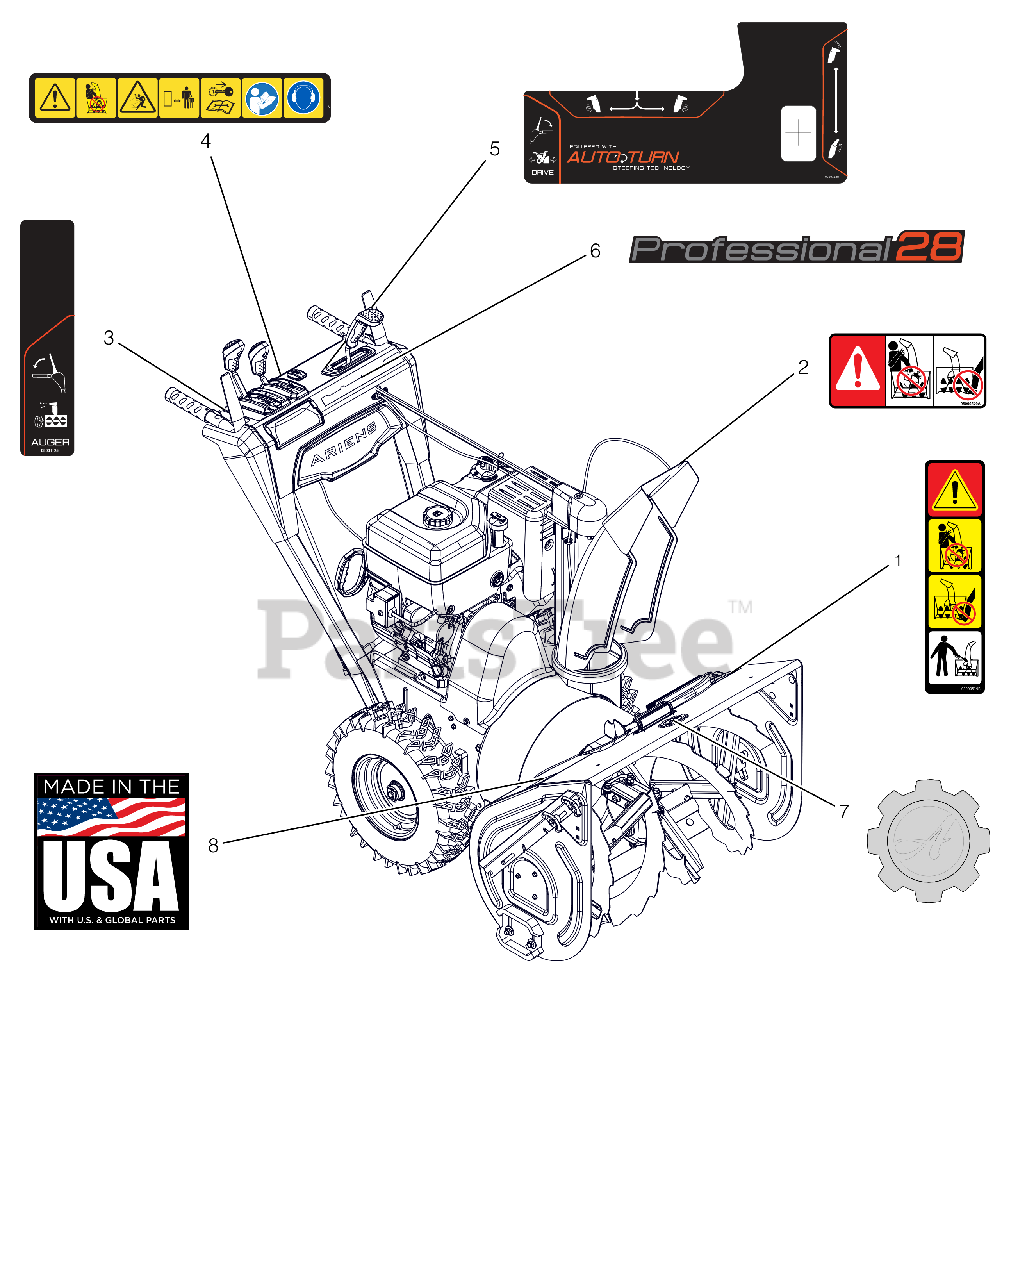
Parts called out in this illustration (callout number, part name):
1	DECAL, DANGER - ROTATING PARTS
2	DECAL, DANGER
3	DECAL,CONTROL-RH CONTROL
4	DECAL,DASH - SAFETY
5	DECAL,CONTROL-LG QT2
6	DECAL, DASH - PRO 28
7	DECAL, ARIENS-GEAR BADGE -THK
8	DECAL, MADE IN USA
